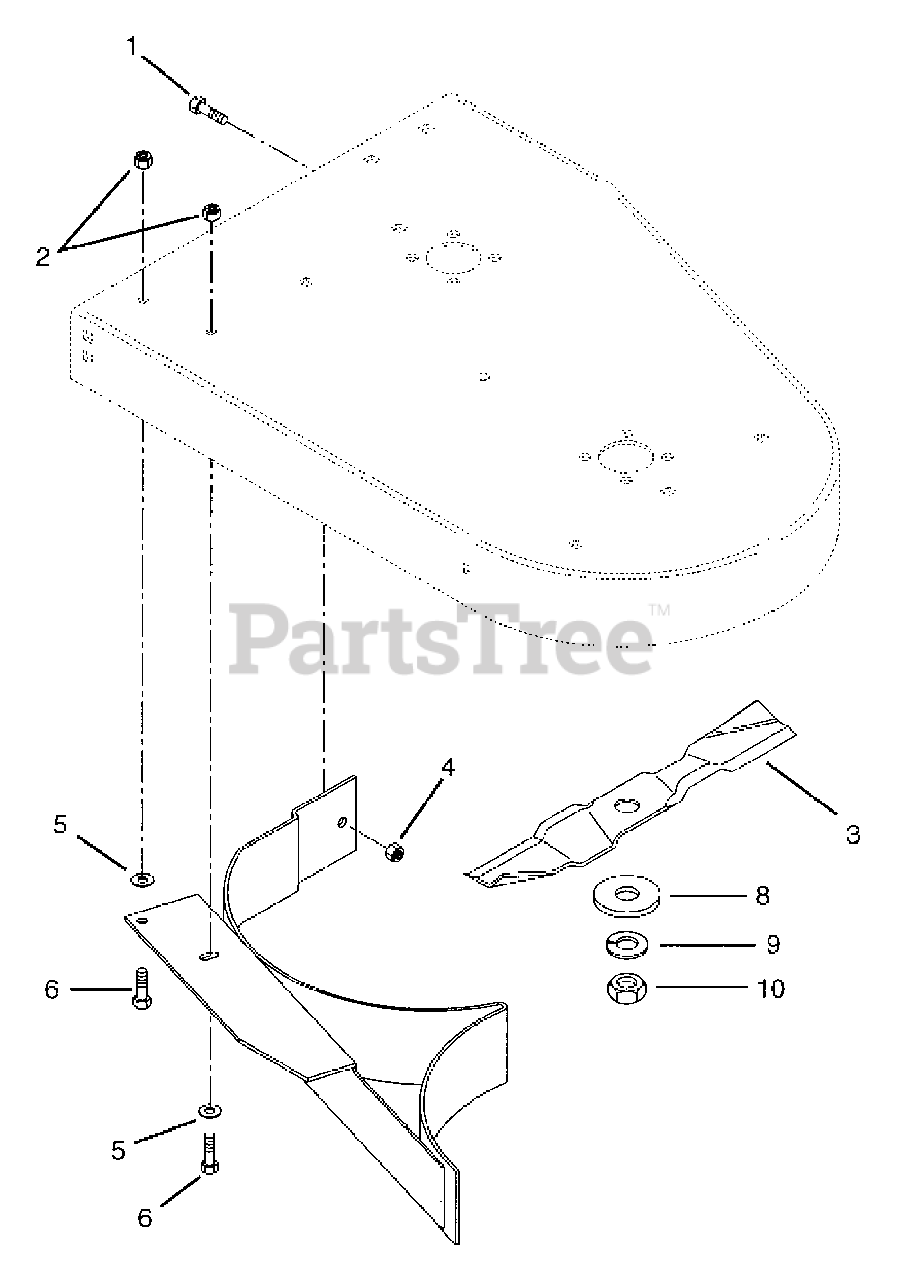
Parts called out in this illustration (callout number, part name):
1	Bolt-Hex .31-18 x .75 Grade 5
2	Nut-Locking-Nylon .375-16 Grade 2
3	Blade, Mulching 36" Blade
4	Nut-Locking-Nylon .312-18 Grade 2
5	Nut-Locking-Center .312-24
6	Bolt-Hex .38-16 x .75 Grade 5
7	Weldment, Mulching Baffle
8	Washer
9	Washer-Locking .625 x .156
10	Nut-Hex .625-11 Grade 2
